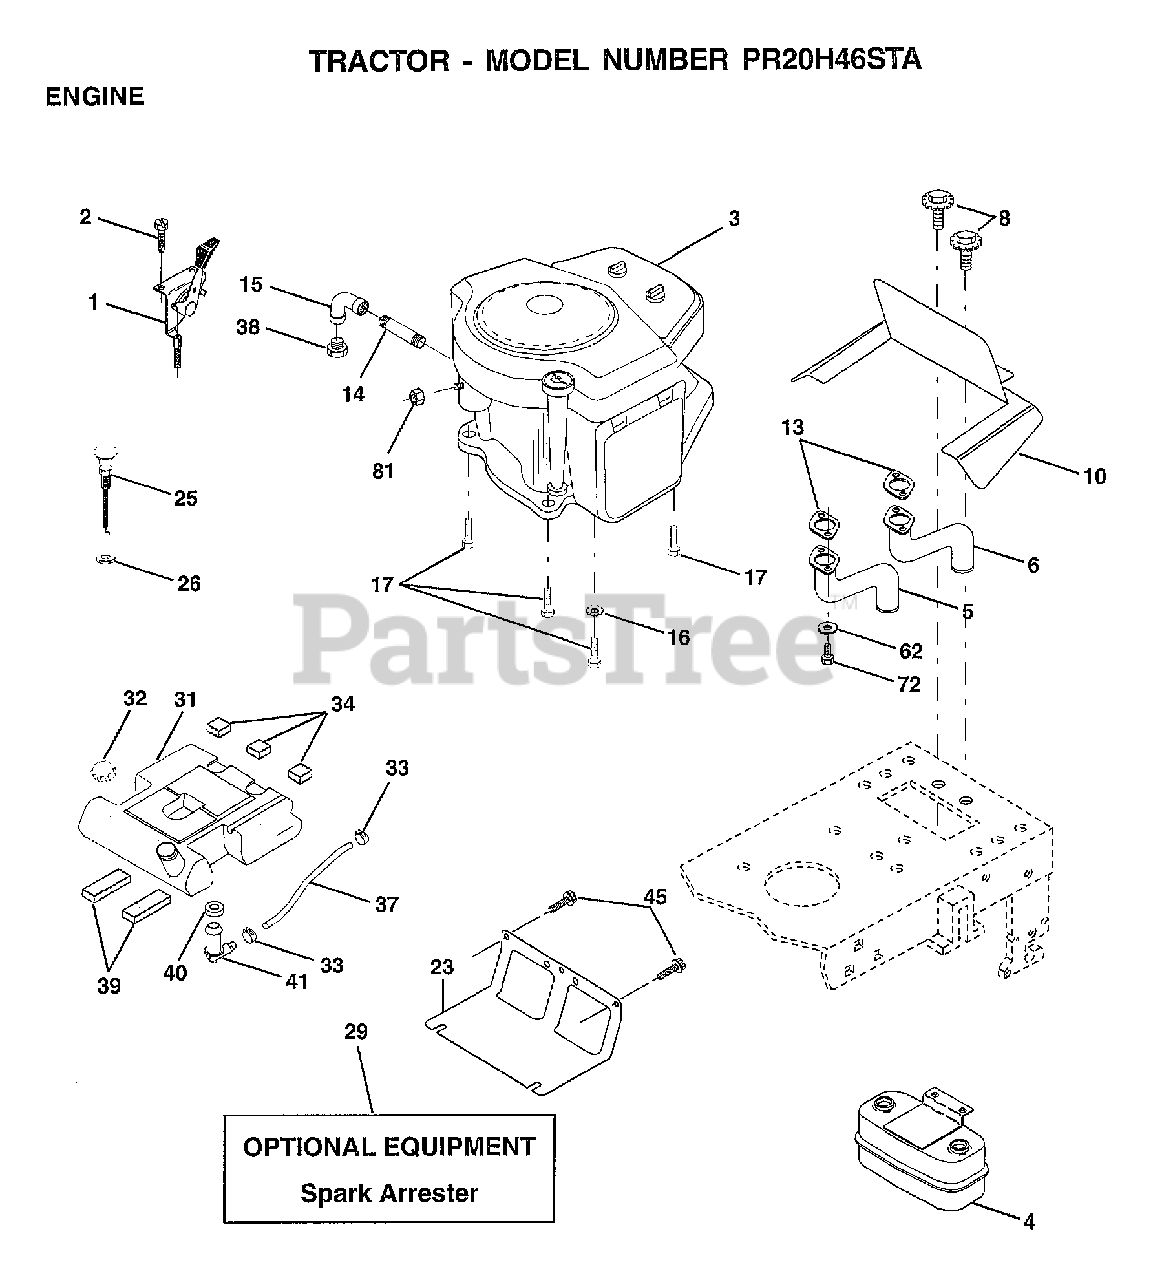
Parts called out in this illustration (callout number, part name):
1	CONTROL THROT. LH
2	SCREW LT
4	MUFFLER.TW.LOTONE
5	TUBE MANIFOLD LH
6	TUBE MANIFOLD RH
8	BOLT.5/16-18.UNC
10	SHIELD.BROWNING
14	PIPE NIPPLE LT
15	ELBOW
16	LOCKWASHER
17	SCREW LT
23	SHIELD BROWNING
25	CONTROL.CHOKE.37
26	"NUT,KEPS 3/8-24IM"
31	TANK FUEL REAR
32	CAP ASM FUEL
33	HOSE CLAMP
34	PAD-SPACER LT
37	FUEL LINE T
39	PAD IDLER TI
40	BUSHING OUTLET T
41	STEM.TANK.FUEL
45	SCREW
62	LOCKWASHER
72	SCREW
81	NUT
